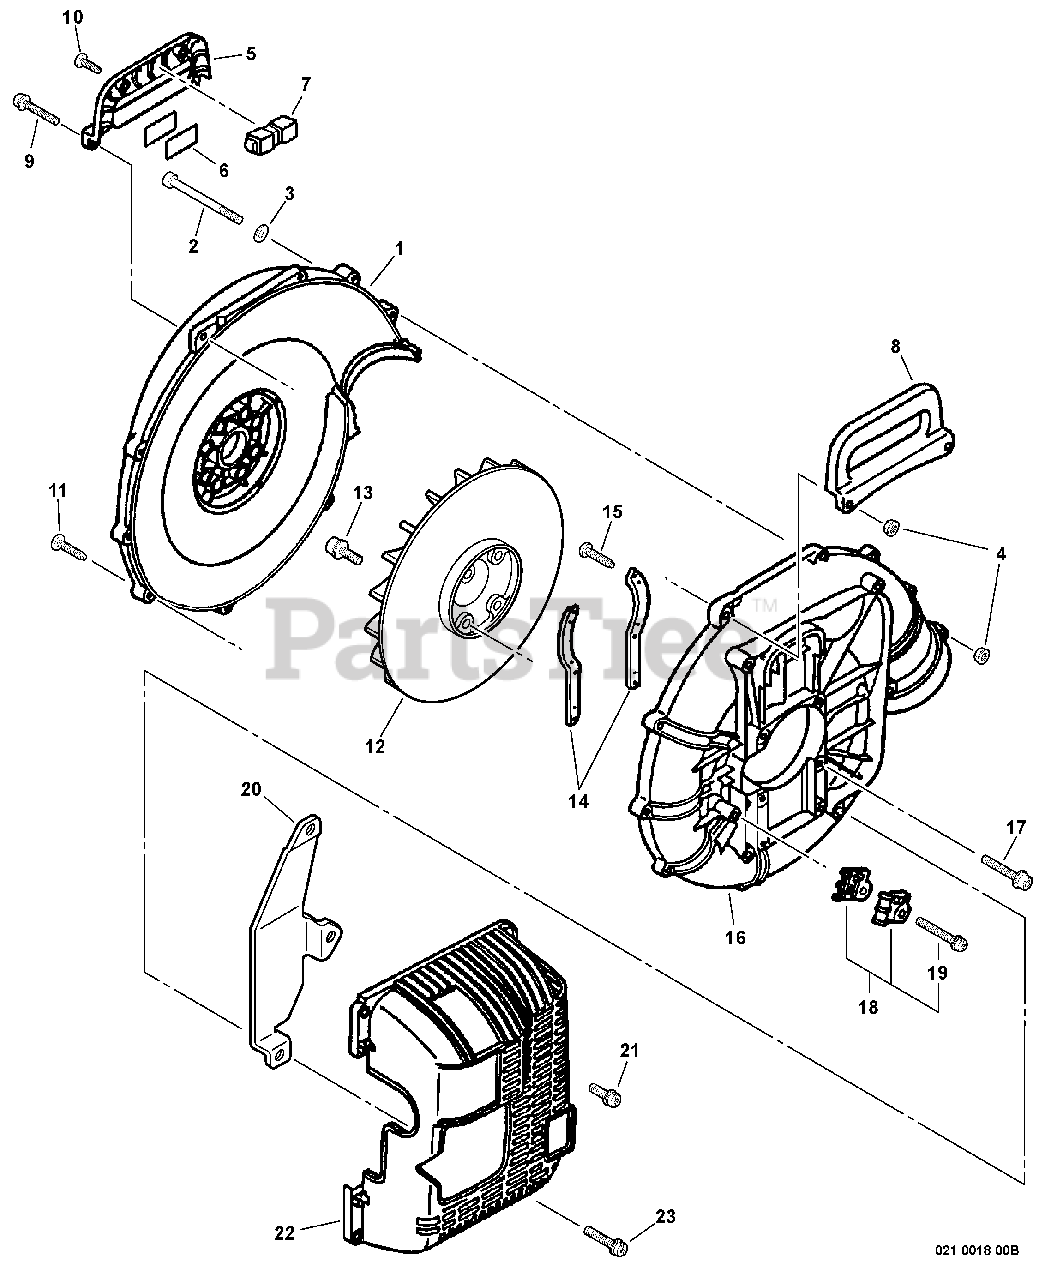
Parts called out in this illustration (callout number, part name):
1	COVER, FAN - INNER
2	BOLT 5×60
3	WASHER 5.3×10×1
4	NUT, FLANGE M5
5	HANDLE
9	SCREW 5×45
10	SCREW 5×16
11	SCREW 5×30
12	FAN
13	BOLT 5×20
14	BRACKET, ENGINE
15	SCREW TAPPING 3×12
16	COVER, FAN - OUTER
17	SCREW 5×32
18	CABLE HOLDER KIT
19	SCREW 5×25
20	INSULATOR
21	SCREW 5×10
22	COVER, ENGINE
23	SCREW 5×18
